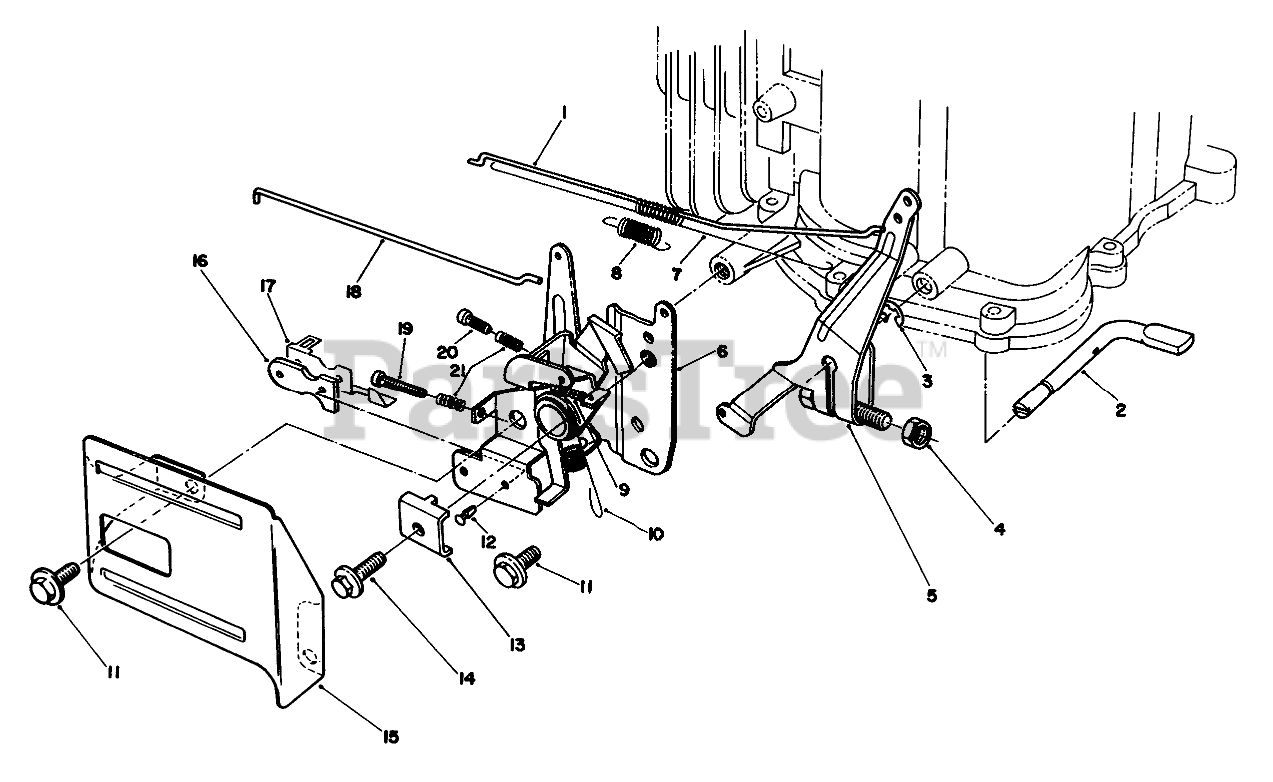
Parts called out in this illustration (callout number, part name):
1	Rod-Carburetor
2	SHAFT
3	E-RING
4	Nut
5	ARM ASM
6	THROTTLE
7	SPRING
8	SPRING
9	SPRING
10	SPRING
12	RIVET
13	CLAMP-CABLE
15	THROTTLE GUARD
16	INSULATOR-KILL SWITCH
17	TERMINAL-KILL SWITCH
18	Rod-Choke
19	SCREW
20	SCREW
21	Spring
